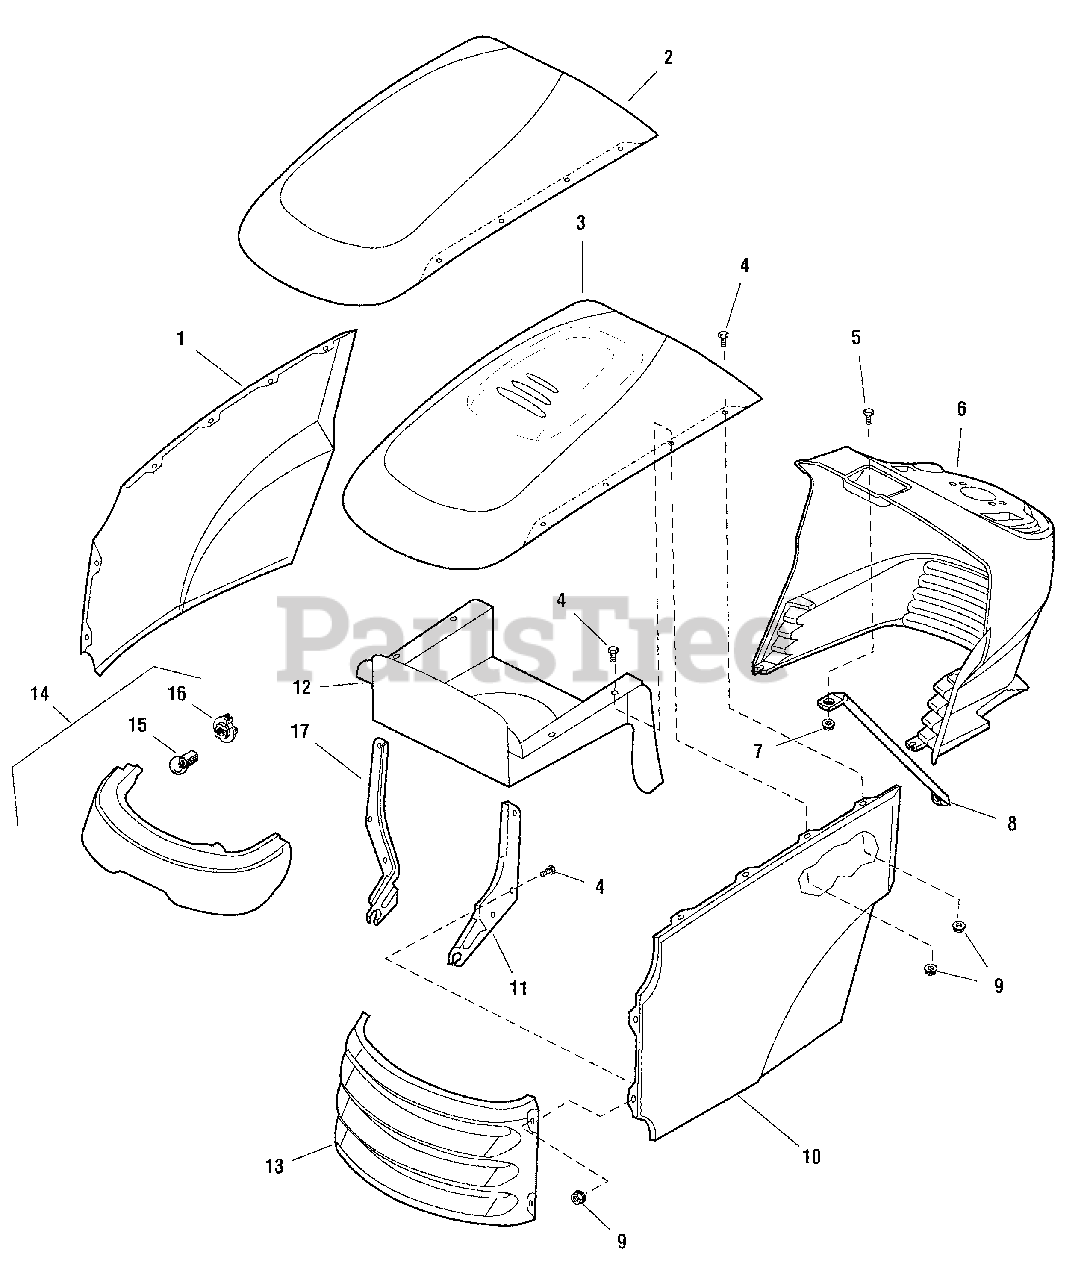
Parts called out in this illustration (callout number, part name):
1	PANEL, RH Side
1	PANEL, RH Side, Red
2	HOOD, no Louvers
2	HOOD, no Louvers, Red
3	HOOD, with Louvers
3	HOOD, with Louvers, Red
4	CAPSCREW, Hex Head Flange Lock,1/4-20 x 5/8
5	SCREW, Phillips Head, #10-24 x 1/2
6	DASHBOARD, With Hole, Black
7	NUT, Hex Nylock,#10-24
8	ROD, Dash Support
9	NUT, Hex Flange Lock, 1/4-20
10	PANEL, LH Side
10	PANEL, LH Side, Red
11	HINGE, LH
12	DUCT, Air Inlet
13	GRILLE, Red
14	HEADLIGHT ASSEMBLY, (Includes Ref. Nos. 15 & 16)
15	BULB, Headligh
16	SOCKET, Headlight
17	HINGE, RH
